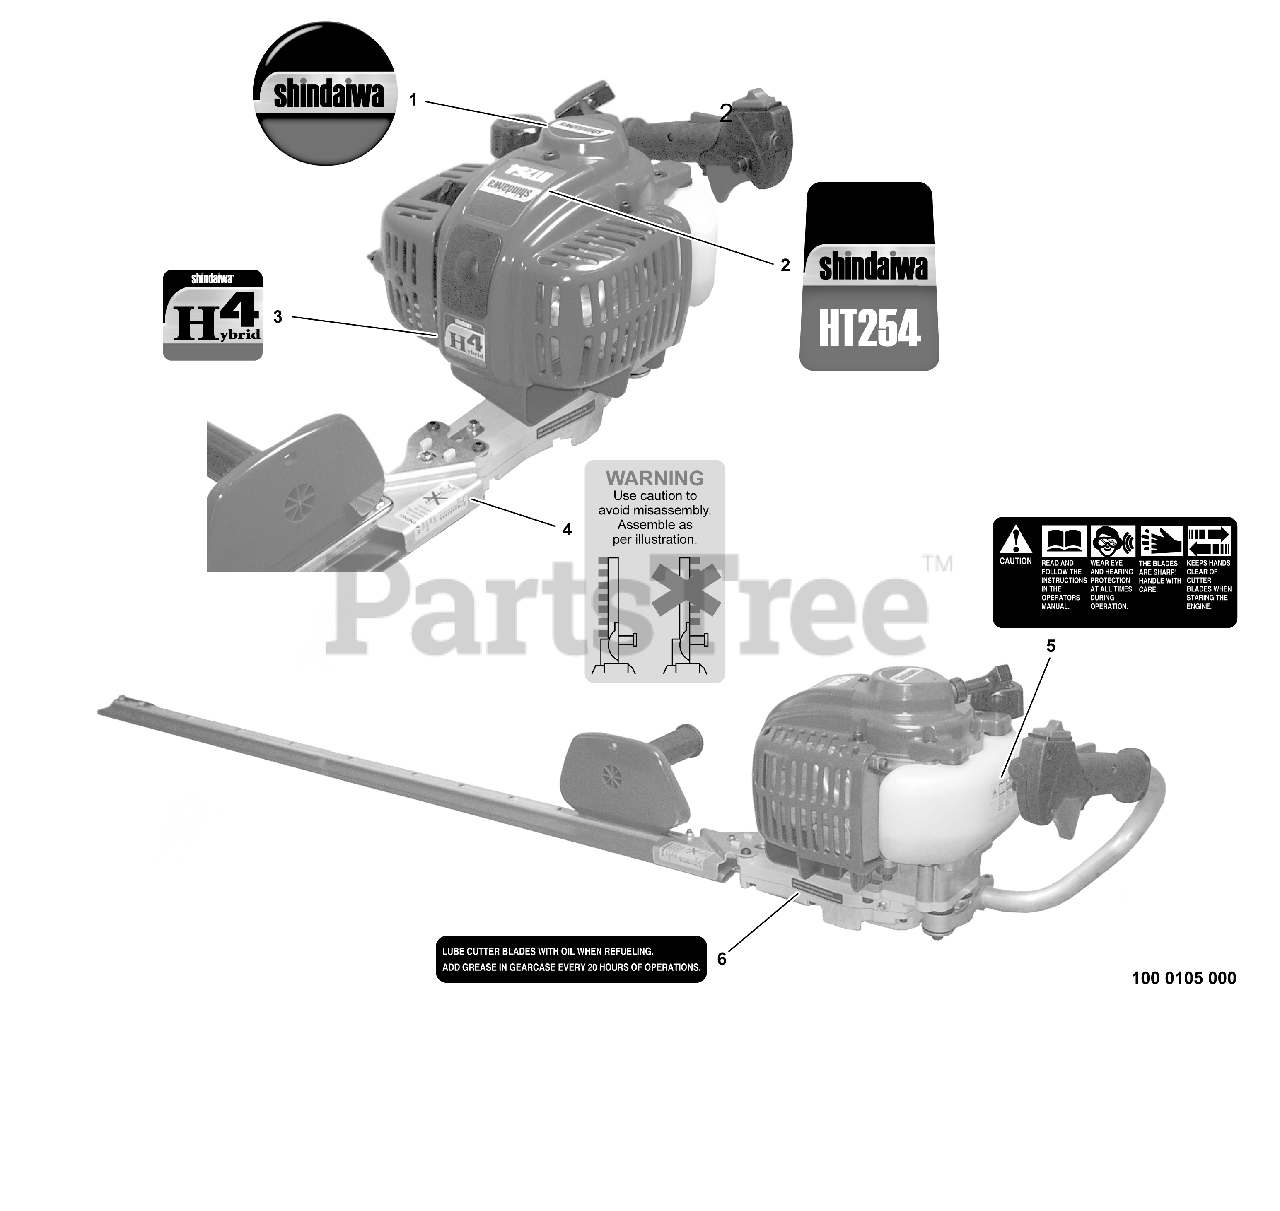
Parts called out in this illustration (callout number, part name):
1	LABEL - SHINDAIWA
2	LABEL - MODEL HT254
3	LABEL - H4
4	LABEL - WARNING
5	LABEL - CAUTION
6	LABEL - BLADE LUBRICATION
